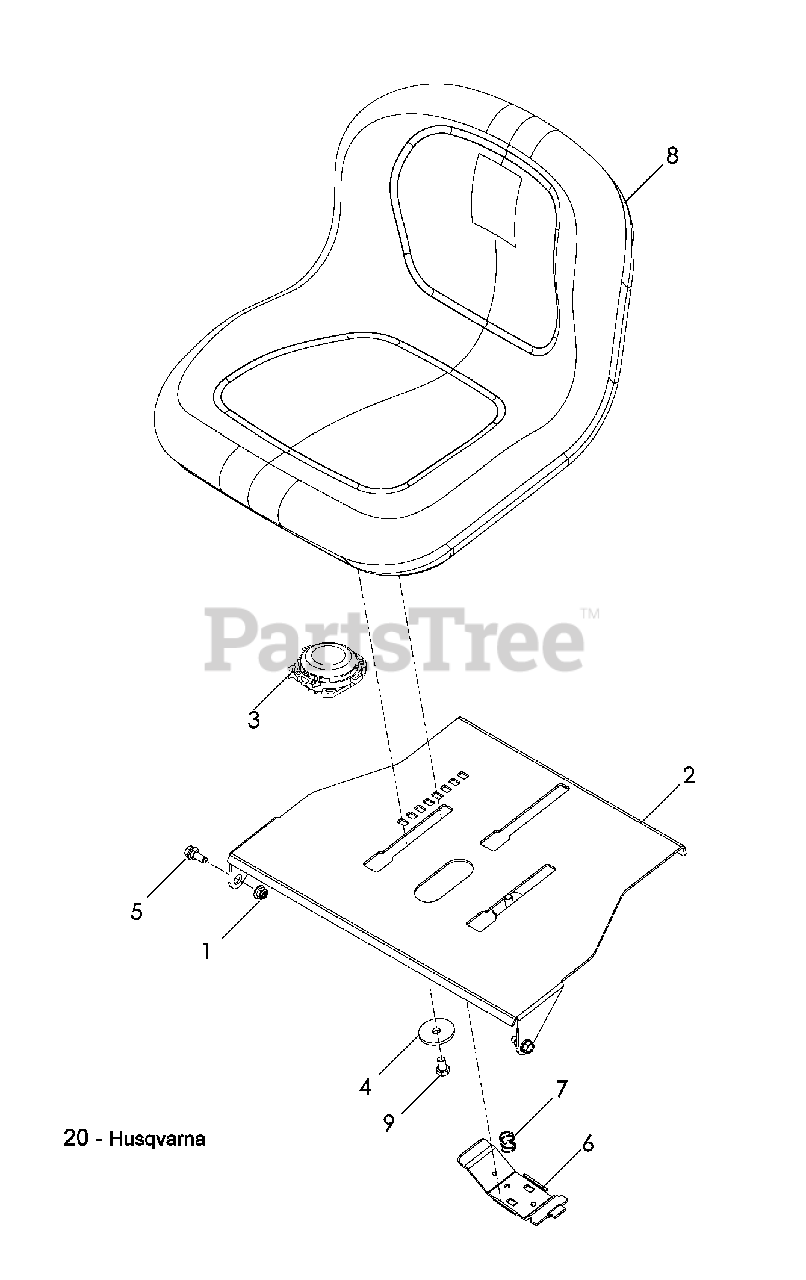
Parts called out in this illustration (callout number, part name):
1	NUT 5/16-18 FLANGE NYLOC
2	PLATE, SEAT
3	SWITCH, SEAT N/C
4	WASHER 3/8 SPECIAL
5	BOLT 5/16-SHOULDER
6	HANDLE, SEAT SLIDE
7	SPRING, SEAT SLIDE
8	SEAT
9	HCS 3/8-16 x 5/8
